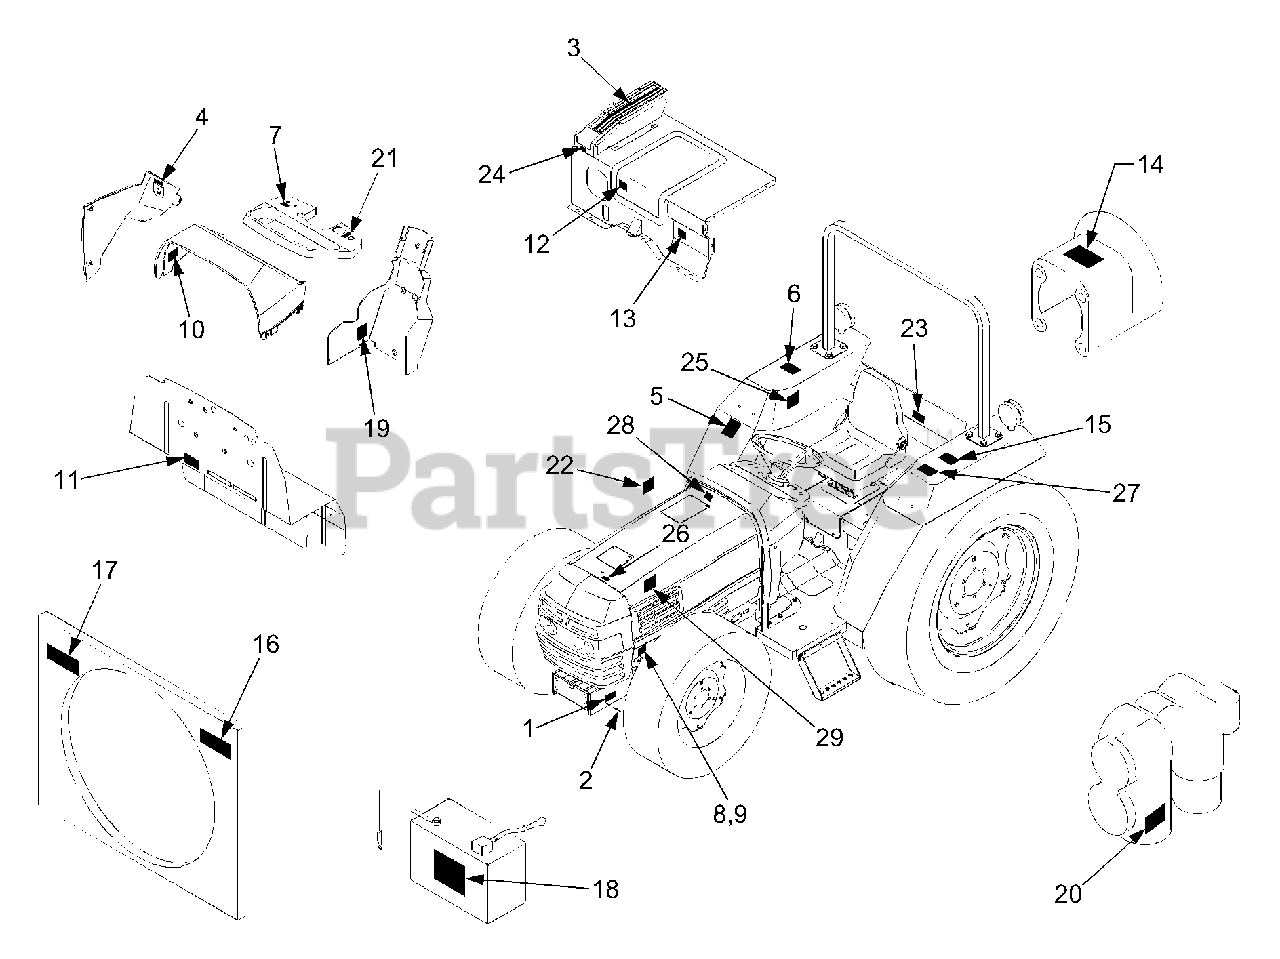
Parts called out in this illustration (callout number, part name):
1	Label, Product
3	Label, Control Valve
4	Label, Start S/W
5	Label, Cartridge
6	Label, Safety
7	Label, PTO Clutch
8	Label 1, Reminder(RH)
10	Label, Parking Brack
11	Label, Fuel Filter
12	Label, Differential
13	Label, Front Wheel
14	Label, PTO Caution
15	Label, Rops Caution
16	Label, Caution(Fan)
17	Label, Muffler
18	Label, Battery
19	Label, Caution
20	Label, Hydraulic Block
21	Label, Caution
22	Label, Cooling Water
23	Label, Coupler Socket
24	Label, Double Lever
25	Label, Speed Control
26	Label, Front Grill
28	Label, Fuel Caution
29	Label, Muffler Caution
